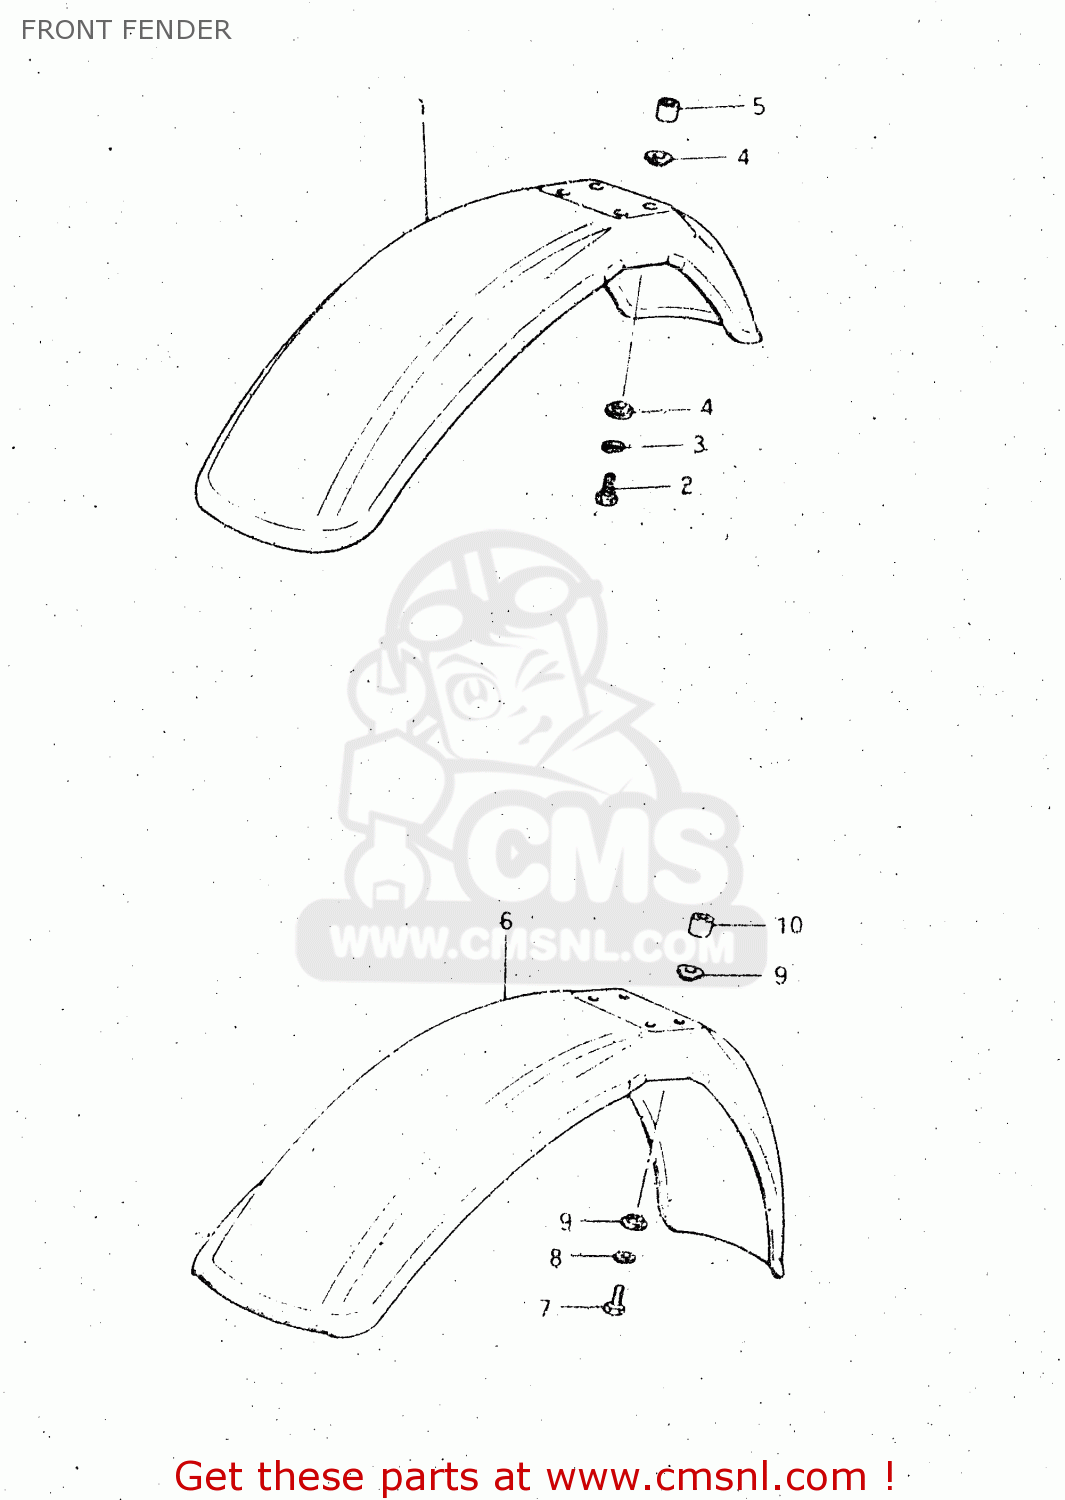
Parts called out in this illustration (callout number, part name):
1	FENDER, FRONT (BLUE)
2	BOLT
3	LOCK WASHER
4	WASHER
5	SPACER (6.8X10X27.4)
6	FENDER, FRONT (BLUE)
7	BOLT
8	LOCK WASHER
9	WASHER
10	SPACER (6.8X10X27.4)
